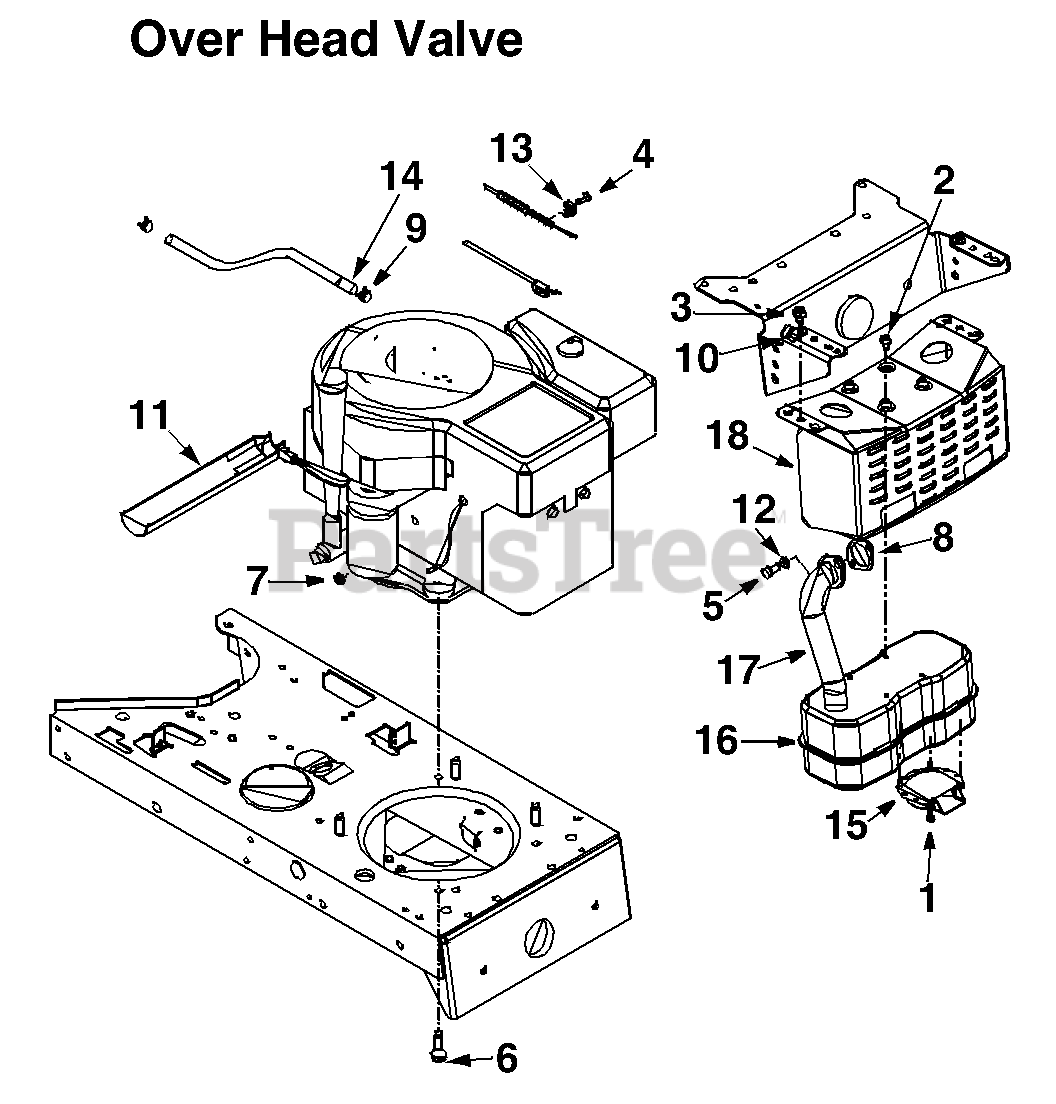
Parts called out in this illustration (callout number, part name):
1	Hex Tap Scr. #8-32 x .38" Lg.
2	Hex TT-Tap Scr. 1/4-20 x .5" Lg.
3	Hex TT-Tap Scr. 5/16-18 x .62"
4	Hex Wash. Scr. #10-32 x .62"
5	Socket Head Scr. 5/16-18 x .62"
6	Hex TT-Tap Scr. 3.8-16 x 1.25"
7	Hex Sems Scr. 1/4-20
8	Gasket
11	Oil Drain Sleeve
12	Lock Washer 5/16 I.D.
13	Casing Clamp
14	Fuel Line
15	Muffler Deflector
16	Muffler
17	Exhaust Pipe
